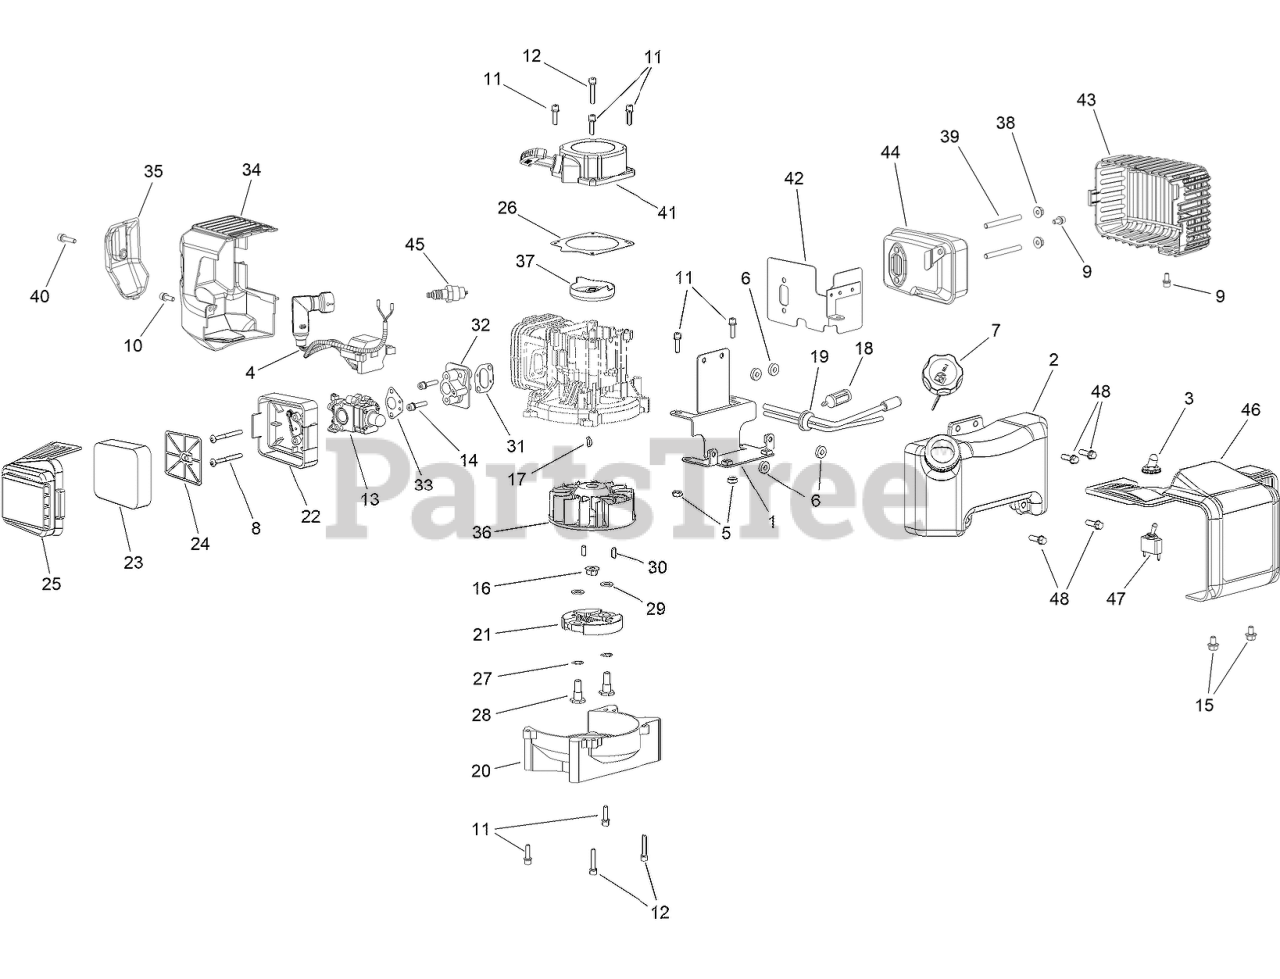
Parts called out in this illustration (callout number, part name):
1	MOUNT-TANK, FUEL
2	FUEL TANK AND CAP KIT
3	COVER-SWITCH
4	COIL-IGNITION
5	SPACER
6	SPACER
7	CAP-FUEL
8	SCREW-BSHCS
9	SCREW-SHCS
10	SCREW-SHCS
11	SCREW-SHCS
12	SCREW-SHCS
13	CARBURETOR
14	SCREW-SHCS
15	SCREW-HHF
17	KEY-WOODRUFF
18	FUEL FILTER
19	FUEL LINE KIT
20	MOUNT-ENGINE
21	CLUTCH SPRING ASM
22	AIR FILTER BASE
23	PREFILTER-FOAM
24	AIR FILTER FRAME
25	COVER-AIR FILTER
26	SPACER-PLATE, RECOIL
27	WASHER-WAVE
28	SCREW-HH
29	WASHER-PLAIN
30	PIN-DOWEL
31	GASKET-INTAKE
32	MANIFOLD-INTAKE
33	GASKET-CARBURETOR
34	SHROUD-ENGINE
35	SHROUD-ENGINE
36	FLYWHEEL
37	CLUTCH-RECOIL
38	NUT-HEX
40	SCREW-SHCS
41	RECOIL ASM
42	SHIELD-MUFFLER
43	GAURD-MUFFLER
44	MUFFLER
45	SPARK PLUG
46	SHROUD-TANK
47	SWITCH
48	SCREW-HHF
